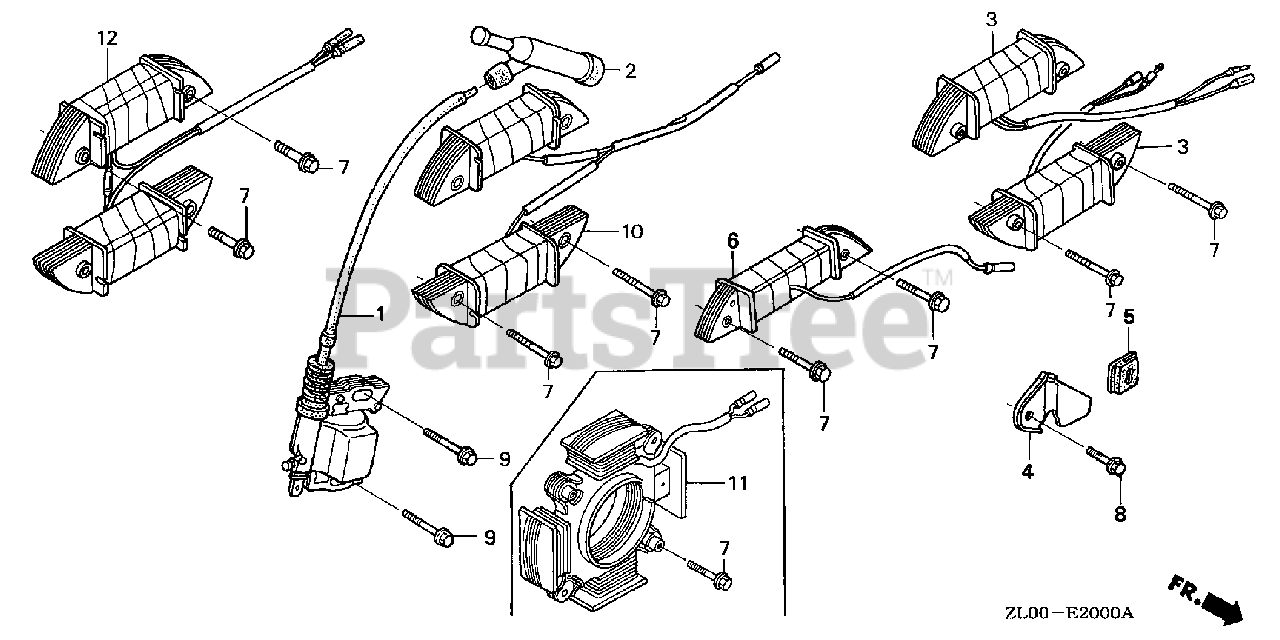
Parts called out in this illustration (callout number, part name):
1	COIL ASSY., IGNITION
2	CAP ASSY., NOISE SUPPRESSOR
4	CLAMP, WIRE
5	GROMMET, WIRE
7	BOLT, FLANGE (6X28)
8	BOLT, FLANGE (5X10)
9	BOLT, FLANGE (6X25)
11	COIL ASSY., CHARGE (12V-7A)
